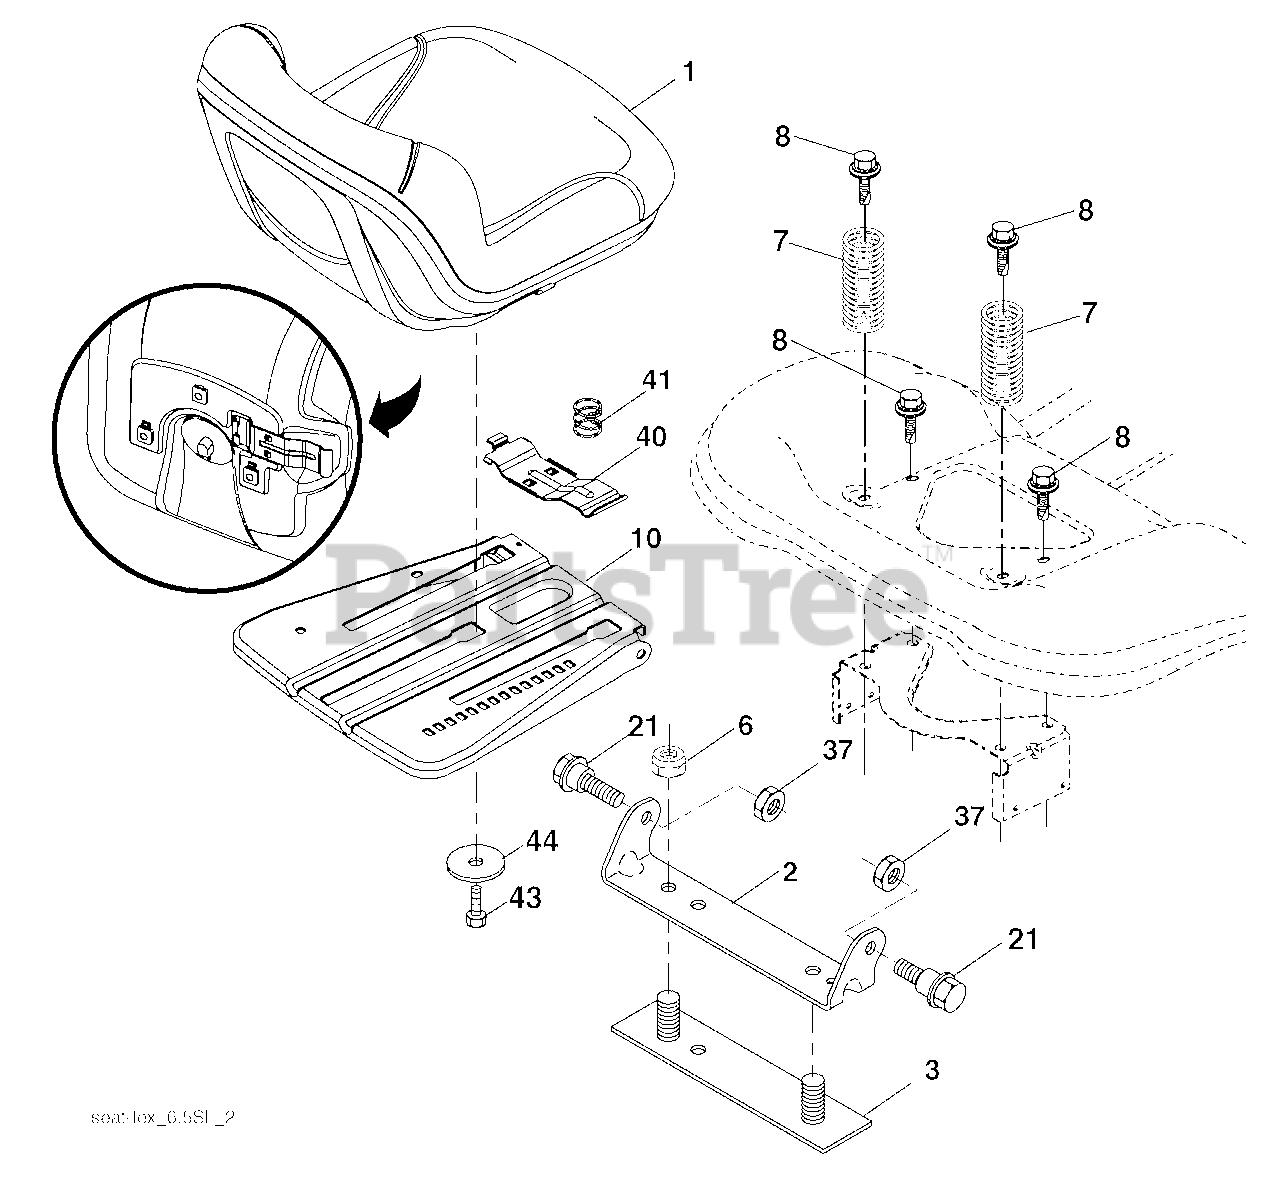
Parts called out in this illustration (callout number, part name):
1	Seat
2	Bracket Pivot Fender
3	Strap, Asm Fender
6	Nut, Lock w/Ins. 3/8-16 unc
7	Spring, Seat Cprsn
8	Bolt 5/16-18 unc x 3/4 w/Sems
10	Pan, Seat
21	Bolt, Shoulder 5/16-18
37	Nut, Lock 5/16-18 unc
40	Handle Slide Seat
41	Spring Latch Seat
43	Bolt Fin Hex 3/8-16 unc x 3/4
44	Washer 13/32 x 2-3/8 x 12 Ga.
